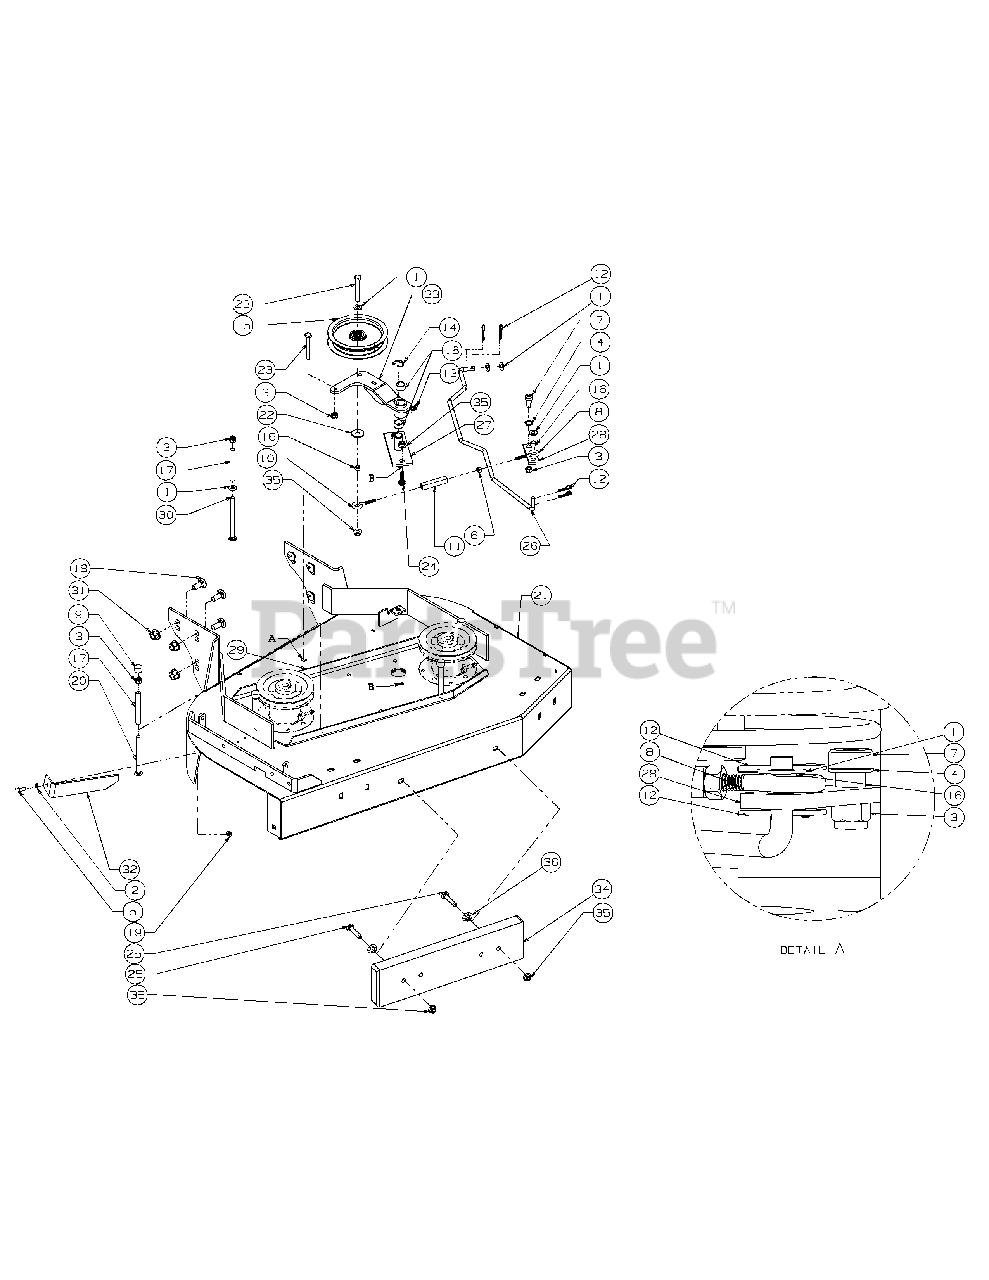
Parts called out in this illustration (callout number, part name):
1	Flat Washer, 3/8 Zinc
2	Flat Washer, 5/16 Zinc
3	Lock Nut, Nylon Insert, 3/8-16
4	Shim Washer
5	Hex Cap Screw, 5/16-18 x .75
6	Hex Nut, 5/16-18
7	Shoulder Bolt
8	Eye Bolt, Right Hand
9	Cap, Black Vinyl
10	Eye Bolt, Left Hand
11	Turnbuckle
12	Hair Pin, 3/8"-1/2"
13	Grease Fitting, 45°, 1/4-28
14	E-Ring, Retainer
15	Idler Deck Take-up
16	Turnbuckle, Sleeve
17	Spacer, Belt Guide
18	Carriage Bolt, 1/2-13 x 1-1/4
19	Nut, Hex Flange Lock, 5/16-18
20	Carriage Bolt, 3/8-16 x 4.5
23	Hex Cap Screw, 3/8-16 x 2.75
24	Carriage Bolt, 3/8-16 x 1-1/4
25	Carriage Bolt, 3/8-16 x 1-1/2
26	Rod Clutch Link
27	Idler Base
31	Nut, Flange Lock, 1/2-13
35	Flange Lock Hex Nut, 3/8-16
36	Push Retainer
